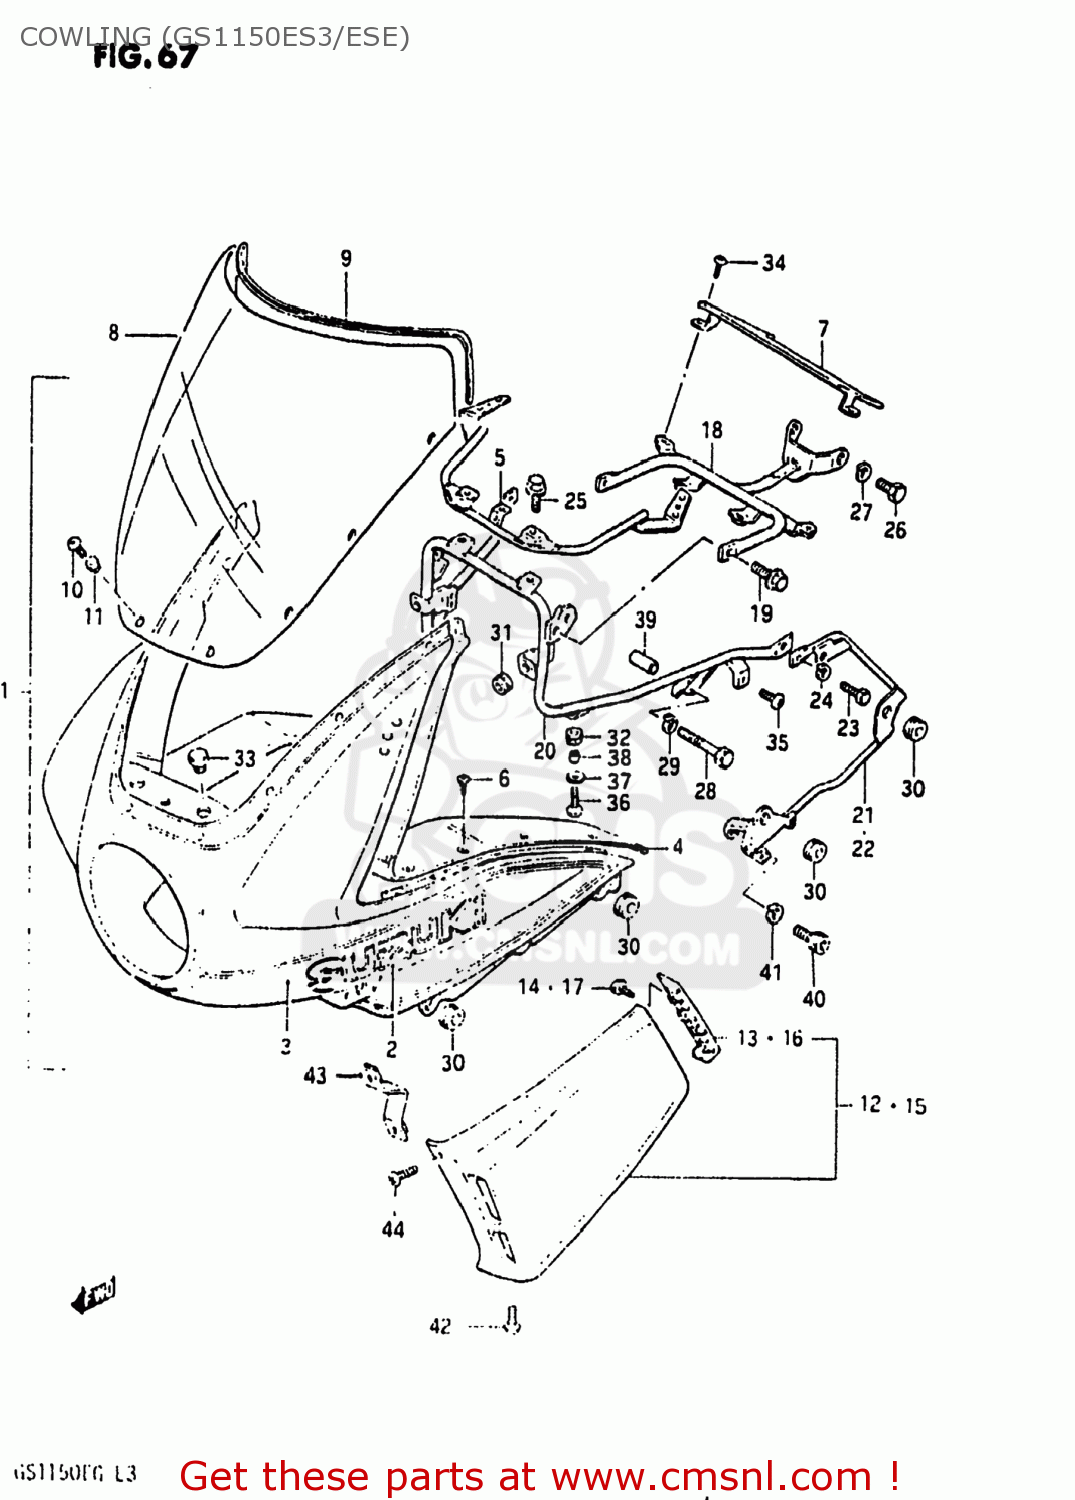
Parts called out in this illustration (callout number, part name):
1	COWLING ASSEMBLY
2	EMBLEM
3	TAPE SET,COWLING
4	PANEL,COWLING
5	BRACE,COWLING BODY
6	SCREW, PANEL
7	COVER,METER,REAR
8	WINDOW,COWLING
9	MOLDING COWLING
10	SCREW(5X20)
11	CUSHION
12	COVER,COWLING SIDE,RIGHT
13	PANEL,COWL SIDE COVER RR RH
14	SCREW
15	COVER,COWLING SIDE,LEFT
16	PANEL,COWLING SIDE COVER
17	SCREW
18	BRACE,COWLING,FRONT
19	BOLT
20	BRACE,COWL RR
21	BRACE,COWLING SIDE,RIGHT
22	BRACE,COWLING SIDE,LEFT
23	BOLT 6X16
24	WASHER,LOCK
25	BOLT
26	BOLT
27	WASHER,LOCK,8.
28	BOLT
29	WASHER,LOCK,8.
30	CUSHION
31	CUSHION
32	CUSHION
33	PLUG(OD:22)
34	SCREW
35	SCREW 6X12
36	SCREW, CENTER
37	WASHER(6.5X18X1)
38	SPACER (6.1X9X9)
39	SPACER (8.6X13.8X35)
40	BOLT
41	WASHER,LOCK,8.
42	SCREW
43	BRACE,SIDE,FRONT
44	SCREW
